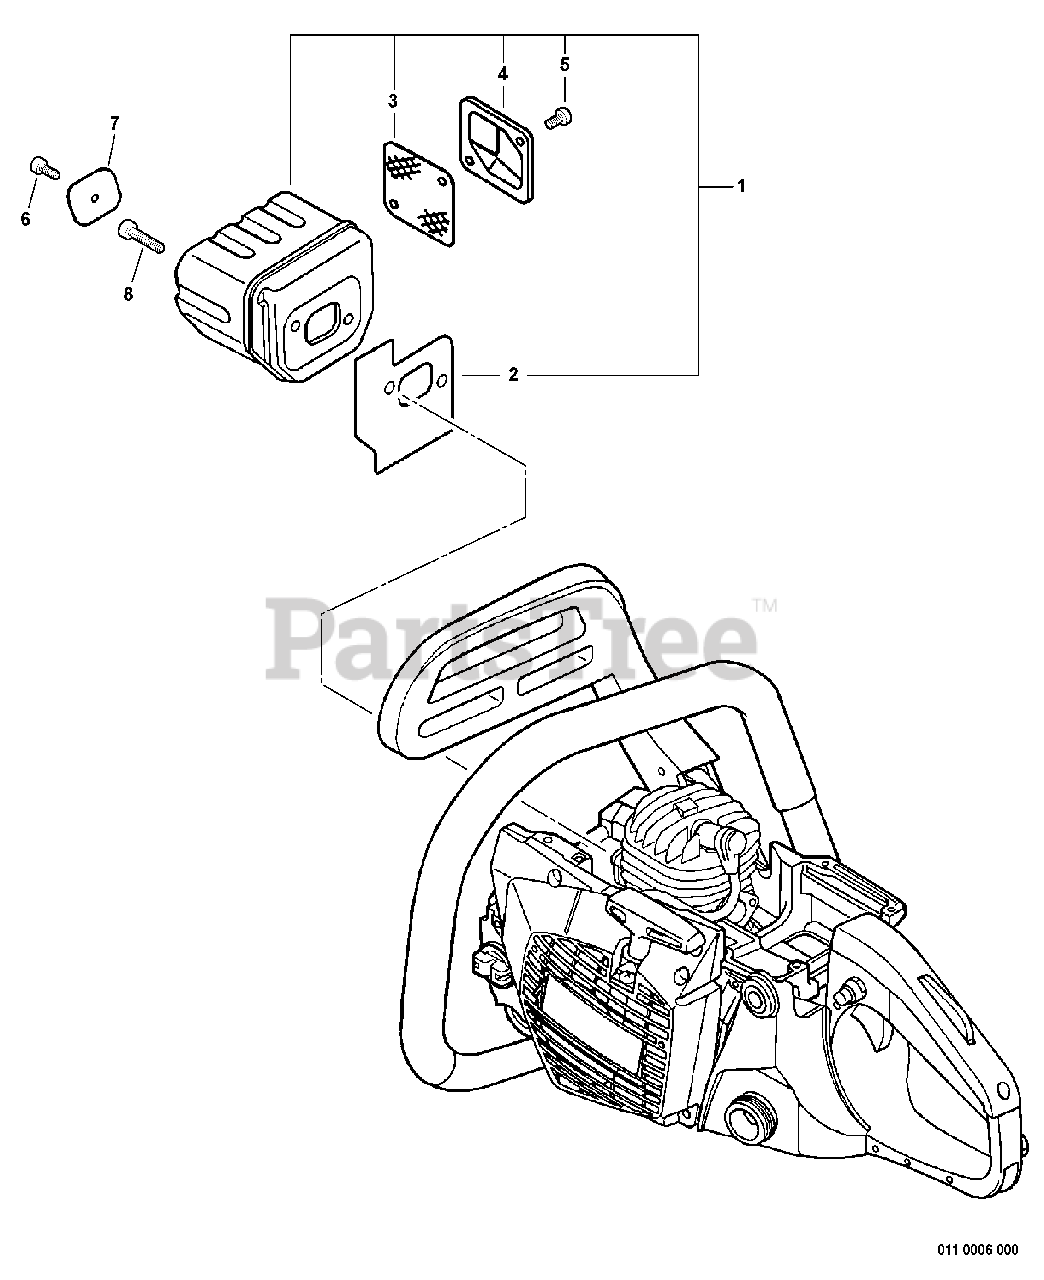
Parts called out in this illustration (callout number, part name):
1	MUFFLER ASSY
2	GASKET, EXHAUST
3	SCREEN, SPARK ARRESTER
4	COVER, MUFFLER
5	SCREW TAPPING 4×8
6	BOLT 4×6
8	BOLT 5×14
